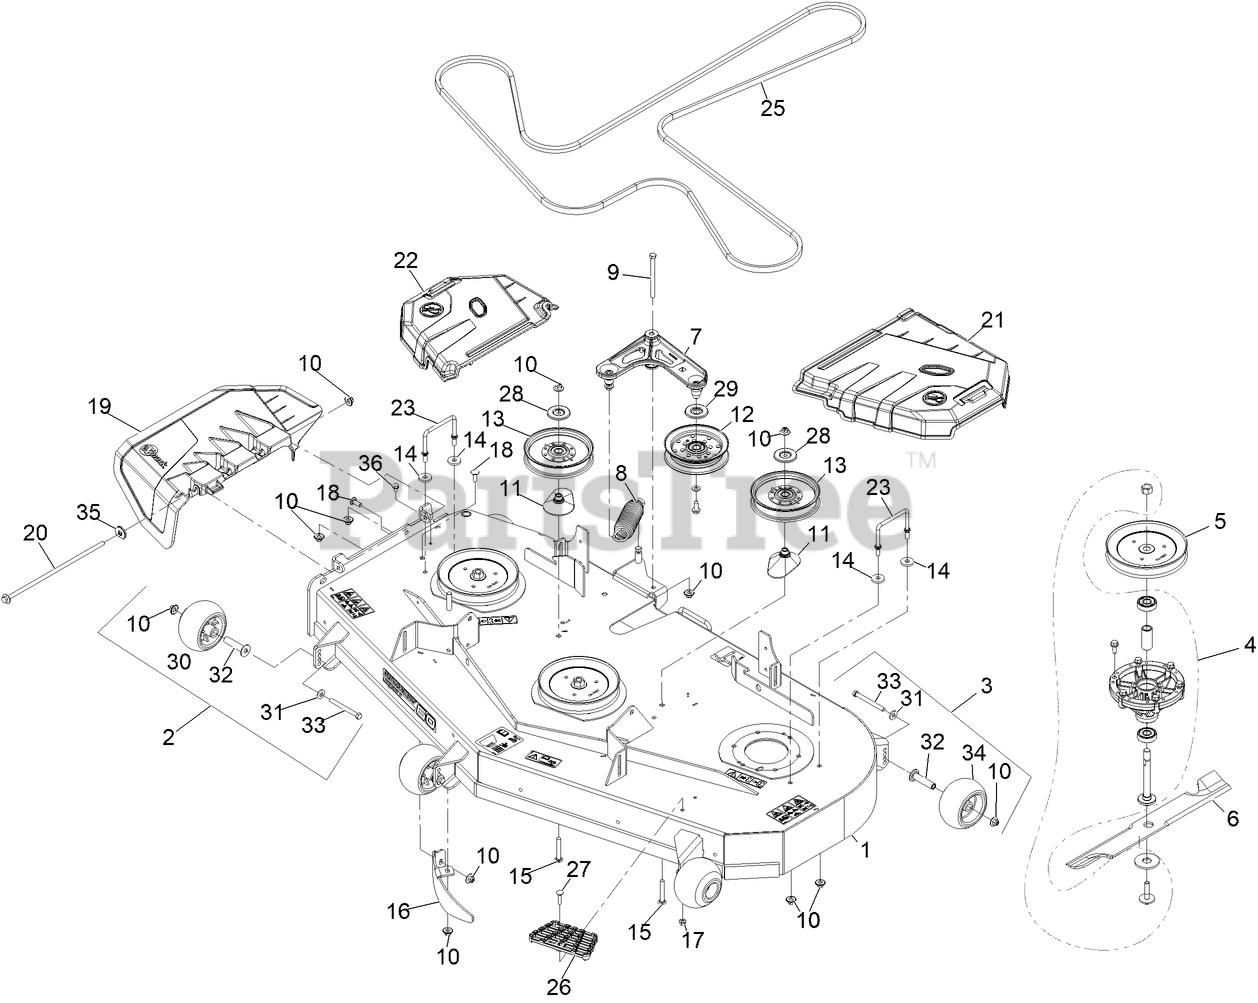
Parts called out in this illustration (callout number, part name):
1	ASM-DECK W/DECALS 603
2	KIT, ANTI-SCALP ROLLER
3	KIT-ANTISCALP ROLLER
4	ASM, CUTTER HOUSING COMPLETE
5	SHEAVE,BLADE DRIVE 7.25
6	Blade-Extreme 2, 20.50"
7	ASM-IDLER ARM W/BEARINGS
8	SPRING-EXTENSION
9	SCREW-HH
10	Nut-Nyloc 3/8-16 Flg
11	SPACER-PULLEY
12	IDLER-PULLEY, FLAT
13	IDLER-PULLEY, FLAT 6.00X1.00
15	SCREW-CARR
16	DOGLEG-603
17	NUT-HF, NI
18	SCREW-CARR
19	Chute-Deck Discharge
20	Pin, Chute
21	SHIELD, LT
22	SHIELD, RT
23	WIREFORM-COVER
26	STEP-DECK
27	Bolt-Carriage 5/16-18 X 1 1/4
28	SHIELD-DUST
29	SHIELD-GUARD, DUST
30	ROLLER-SCALP, ANTI
31	WASHER-BELLEVILLE
32	AXLE, ROLLER
33	SCREW-HH 3/8-16 X 3 3/4 GR 8
34	ROLLER-SCALP, ANTI
35	Retainer, Chute
36	SCREW-HHF
